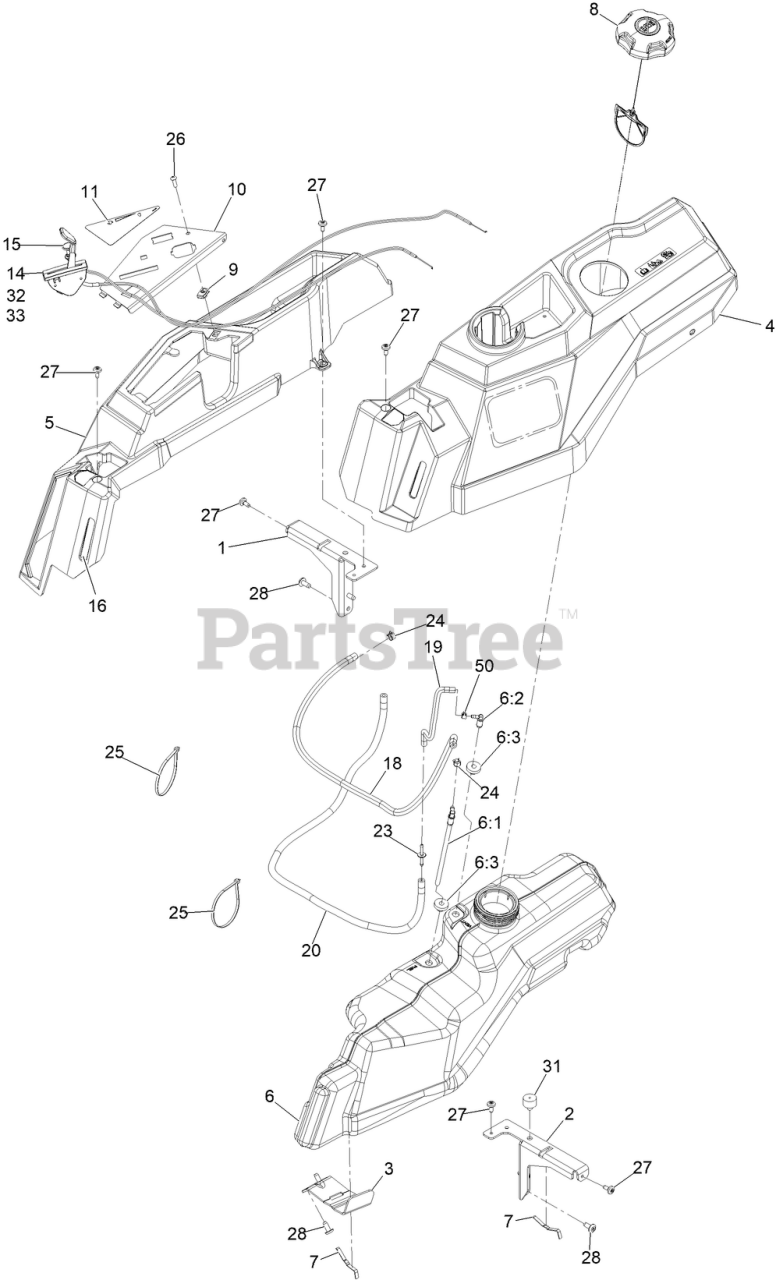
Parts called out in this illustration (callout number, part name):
1	SUPPORT-POD, RH
2	SUPPORT-POD, LH
3	SUPPORT-TANK, FUEL
4	POD- LH
5	POD- RH
6	TANK-FUEL ASM
6:1	Connector-Elbow, 90 DEG
6:2	Fitting-Elbow 90
6:3	BUSHING
7	SPRING
8	CAP-FUEL, RATCHETING
10	PANEL- CONTROL
11	DECAL-CONTROL PANEL
14	ASM,THROTTLE CABLE
15	CABLE-CONTROL, CHOKE
16	PLUG-SC
18	HOSE-FUEL
19	Hose-Fuel
20	Hose, Fuel
23	Adapter Orifice
24	CLAMP-HOSE
25	TIE-CABLE
26	SCREW-PRH
27	SCREW-SHOULDER
31	BUMPER-GROMMET
32	SCREW-PPH
33	NUT-LOCK, NI
50	CLAMP-HOSE
